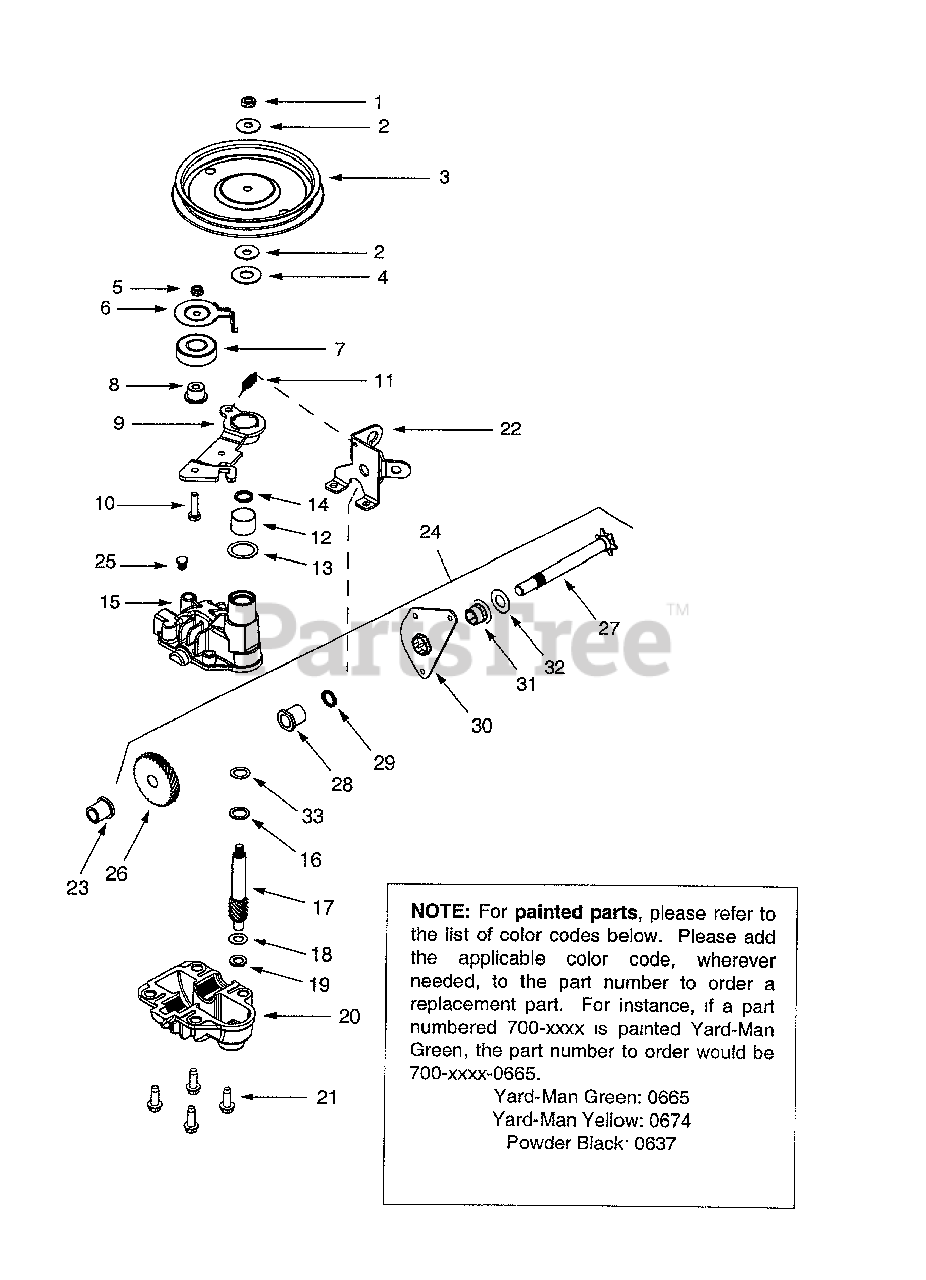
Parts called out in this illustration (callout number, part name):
1	Hex Jam Nut, 5/16-24
2	Bell Wash. .325 x .930 x .045
3	Pulley
4	Fl. Wash .510 x 1.120 x .060
5	Hex Jam Nut, 1/4-28
6	Belt Keeper
7	Bearing
8	Flange Spacer
9	Idler Bracket Assembly
10	Hex Cap Scr. 1/4-28 x 1.00 Gr. 5
11	Extension Spring
12	Bearing Sleeve
13	Fl. Wash. .885 x 1.145 x.030
14	Oil Seal
15	Upper Housing Assembly
16	Thrust Wash. .504 x .700 x .030
17	Pinion Shaft, 10 T.
18	Thr. Wash. 3/8 x .70 x .030
19	Thr: Wash. .388 x .625 x .062
20	Lower Housing Assembly
21	Hex Scr. 1/2-20 x .75
24	Shaft Assembly
26	Gear 34 T.
27	Output Shaft, 6 T.
28	Flange Bearing
29	Oil Seal
30	Pivot Bracket
31	Flange Bearing
32	Flat Washer
33	Bearing
